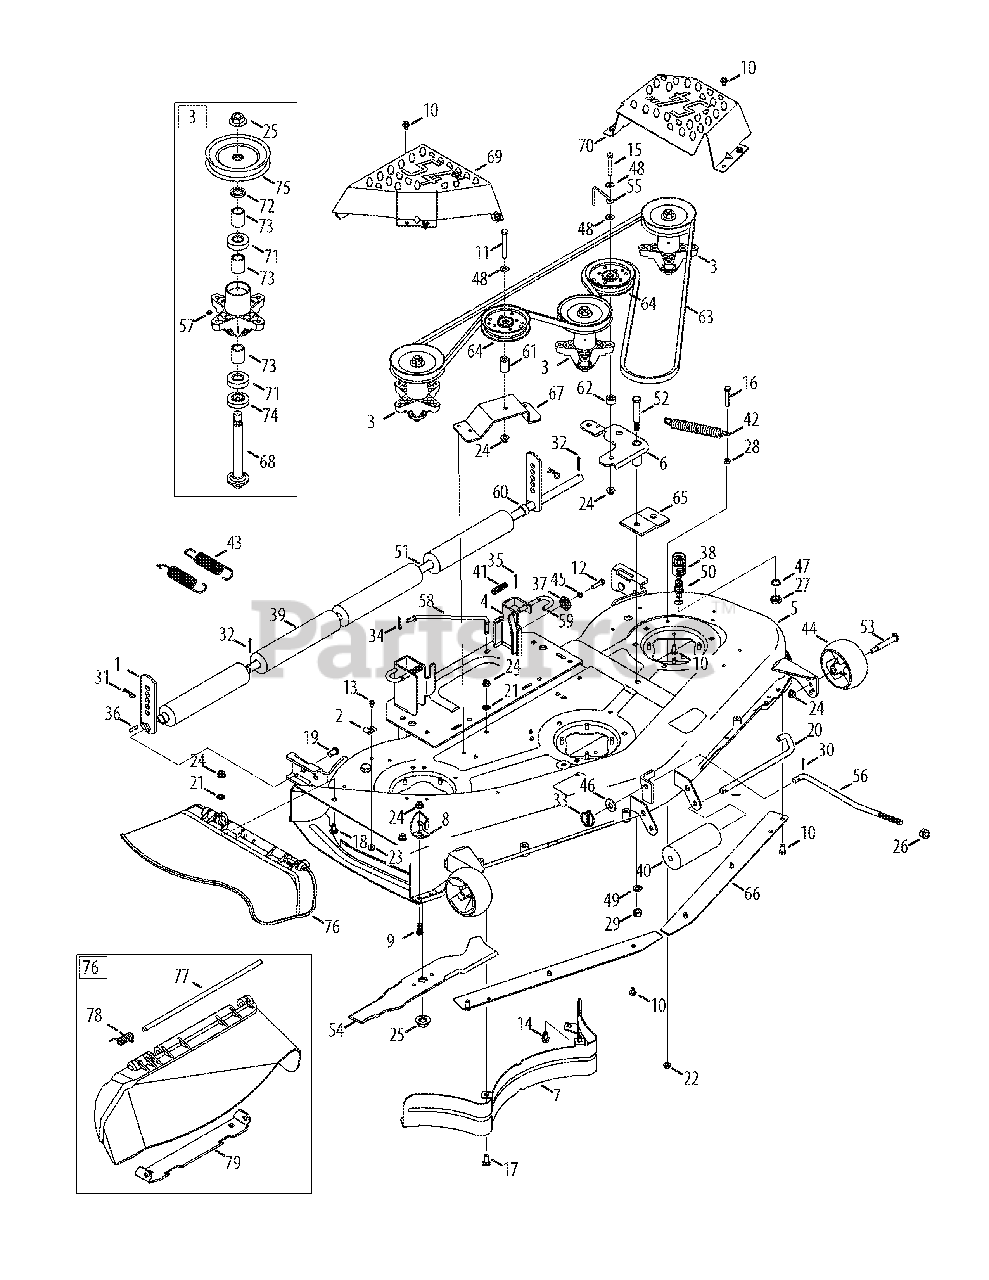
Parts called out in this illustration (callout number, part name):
1	Height Adjust Bracket
2	Retainer Hook Bracket
3	Spindle Assembly
4	Deck Hanger Bracket Assembly
5	Deck Assembly
6	Idler Assembly
7	Inner Baffle
8	Deflector Chute Stop
9	Hex Screw, 3/8-16:1.00
10	Taptite Screw, 5/16-18:.750
11	Hex Screw, 3/8-16:3.00
12	Hex Screw, 5/16-18:1.25
13	Hex Screw, 1/4-20:1.00
14	Taptite Screw, 3/8-16:0.750
15	Hex Screw, 3/8-16:2.50
16	Hex Screw, 5/16-18:2.00
17	Carriage Bolt, 3/8-16:1.00
18	Carriage Bolt, 3/8-16:0.75
19	Clevis Pin, .50 DIA x .78 LG
20	Roller Pin, 1/2 DIA x 7.31 LG
21	Push Nut, 3/8
22	Flangelock Nut, 5/16-18
23	Flangelock Nut, 1/4-20
24	Flangelock Nut, 3/8-16
25	Flange Nut, 5/8-18
26	Flexlock Nut, 1/2-13
27	Hex Nut, M16-1.5 DIN 936
28	Hex Nut, 5/16-18
29	Hexlock Nut, Counterlock, 1/2-13
30	Cotter Pin, 3/32:1.0
31	Click Pin, .092 x 1.64 LG
32	Cotter Pin, 5/32:1.25
33	Lynch Pin, .1875
34	Bow Tie Cotter Pin
35	Cotter Pin, 1/8 x 1.25
36	Spring Pin, 1/4 DIA x 1.00 LG
37	Deck Gear
38	Water Nozzle Adaptor
39	Deck Roller
40	Front Roller
41	Compression Spring, .535 OD x 1.751 LG
42	Extension Spring, .85 OD x 5.915 LG
43	Extension Spring, 1.15 OD x 5.99 LG
44	Deck Wheel
45	Lock Washer, 5/16
46	Flat Washer, .531 x 1.25 x .100
47	Lock Washer, 5/8
48	Flat Washer, .406 x .875 x .059
49	Lock Washer, 1/2
50	Deck Water Nozzle
51	Shaft, .750 x .47.12
52	Shield Screw, .625 x 2.50:1/2-13
53	Shoulder Bolt, .496 x 2.50:3/8-16
55	Belt Keeper Rod
56	Deck Lift Rod
57	Lube Fitting
58	Deck Sway Rod
59	Deck Release Handle Rod
60	Spacer, .82 ID x 1.00 OD x .53
61	Spacer, .380 x .900 x 1.313
62	Spacer, .385 ID x .88 x .64
63	V Belt
64	Idler Pulley, 4.25"DIA
65	Pulley Stabilizer Bracket
66	Deck Skirt
67	Stationary Idler Bracket
68	Spindle Shaft, 6.95 LG
69	RH Spindle Cover
70	LH Spindle Cover
71	Ball Bearing, .787 ID x 1.85 OD x .551
72	Spacer, .790 ID x 1.25 OD x .175
73	Spacer, .80 x 1.10 x 1.322 LG
74	Spacer, .79 x 1.82 x .55 LG
75	Deck Pulley
76	Chute Assembly
77	Hinge Pin
78	Torsion Spring, .44 ID x 2.0
79	Chute Bracket
